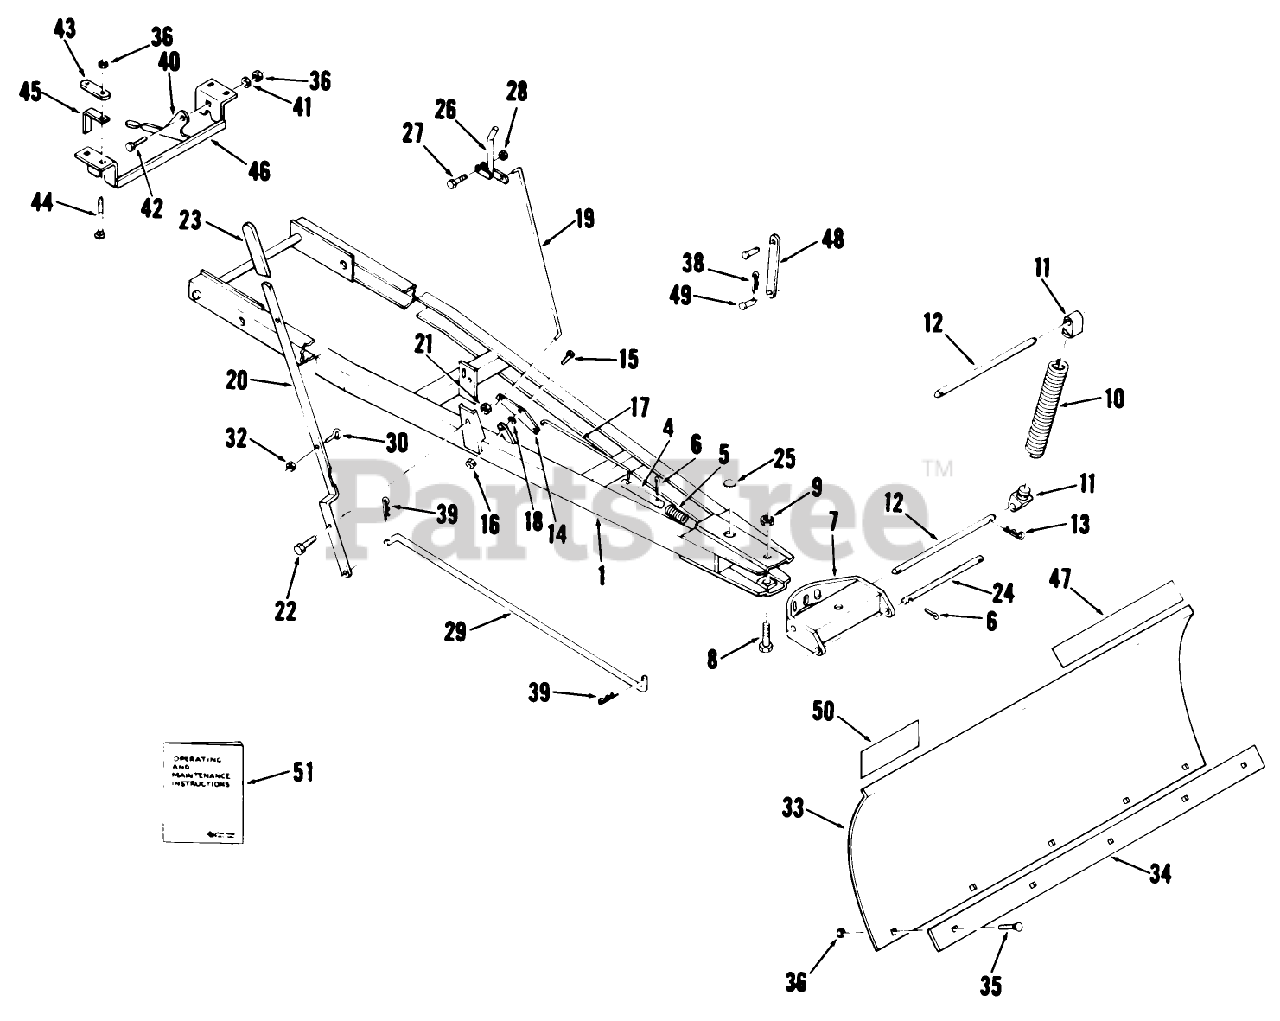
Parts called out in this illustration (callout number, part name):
1	ASSY-FRAME *R
5	SPRING-COMPRESSION
12	ROD-PIVOT, BLADE
13	Hairpin
17	LOWER INDEX ROD
23	GRIP
24	ROD-LOWER
25	PLUG
30	EYEBOLT
33	ORD 109593 & 109596
38	Hairpin Cotter
39	Hairpin
40	PLATE-LATCHING
43	BRACKET-REAR LINK MOUNTING
45	SPACER-BRACKET
47	DECAL-REAR
48	LINK-LIFT
51	Operating and Maintenance Instructions (42 in./107 cm Blade Only)
51	Operating and Maintenance Instructions
